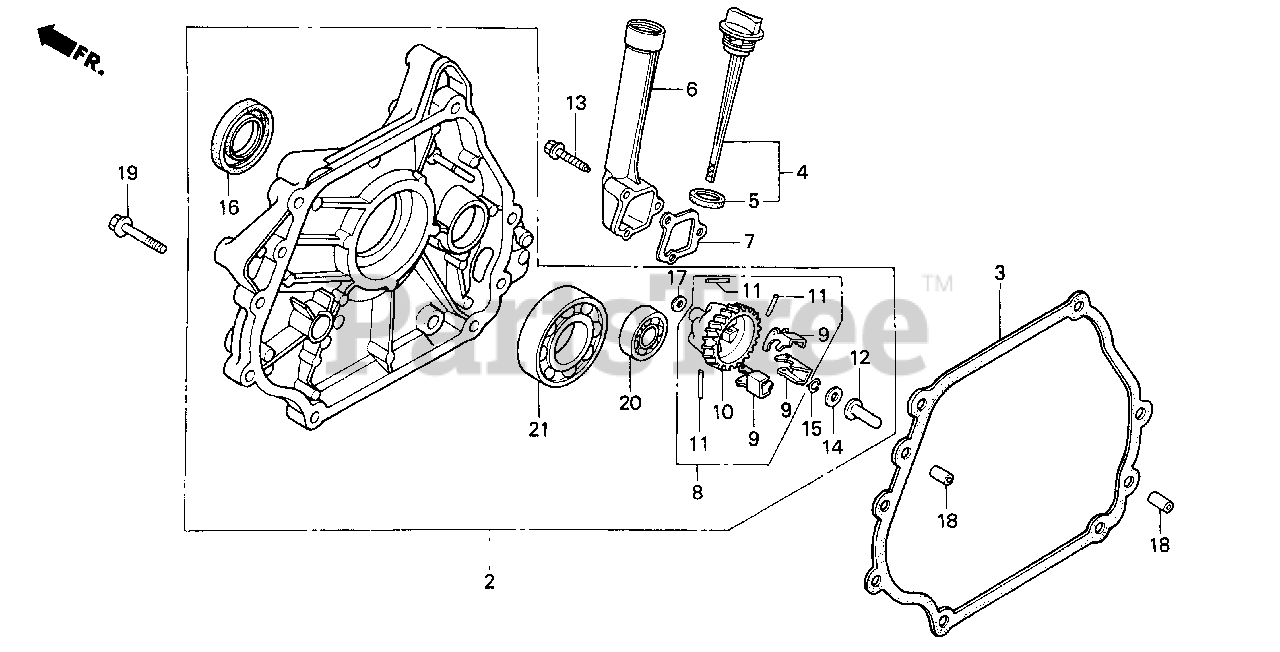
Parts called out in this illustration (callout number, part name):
2	COVER ASSY., CRANKCASE
3	GASKET, CASE COVER
4	CAP ASSY., OIL FILLER
5	GASKET, OIL FILLER CAP
6	EXTENSION, OIL FILLER
7	GASKET, OIL FILLER EXTENSION
8	GOVERNOR ASSY.
9	WEIGHT, GOVERNOR
10	HOLDER, GOVERNOR WEIGHT
11	PIN, GOVERNOR WEIGHT
12	SLIDER, GOVERNOR
13	BOLT, FLANGE (6X40) (CT200)
15	CLIP, GOVERNOR HOLDER
16	OIL SEAL (35X52X8)
17	WASHER, PLAIN (6MM)
18	PIN, DOWEL (8X12)
19	BOLT, FLANGE (8X40)
20	BEARING, RADIAL BALL (6202)
21	BEARING, RADIAL BALL (6207)
